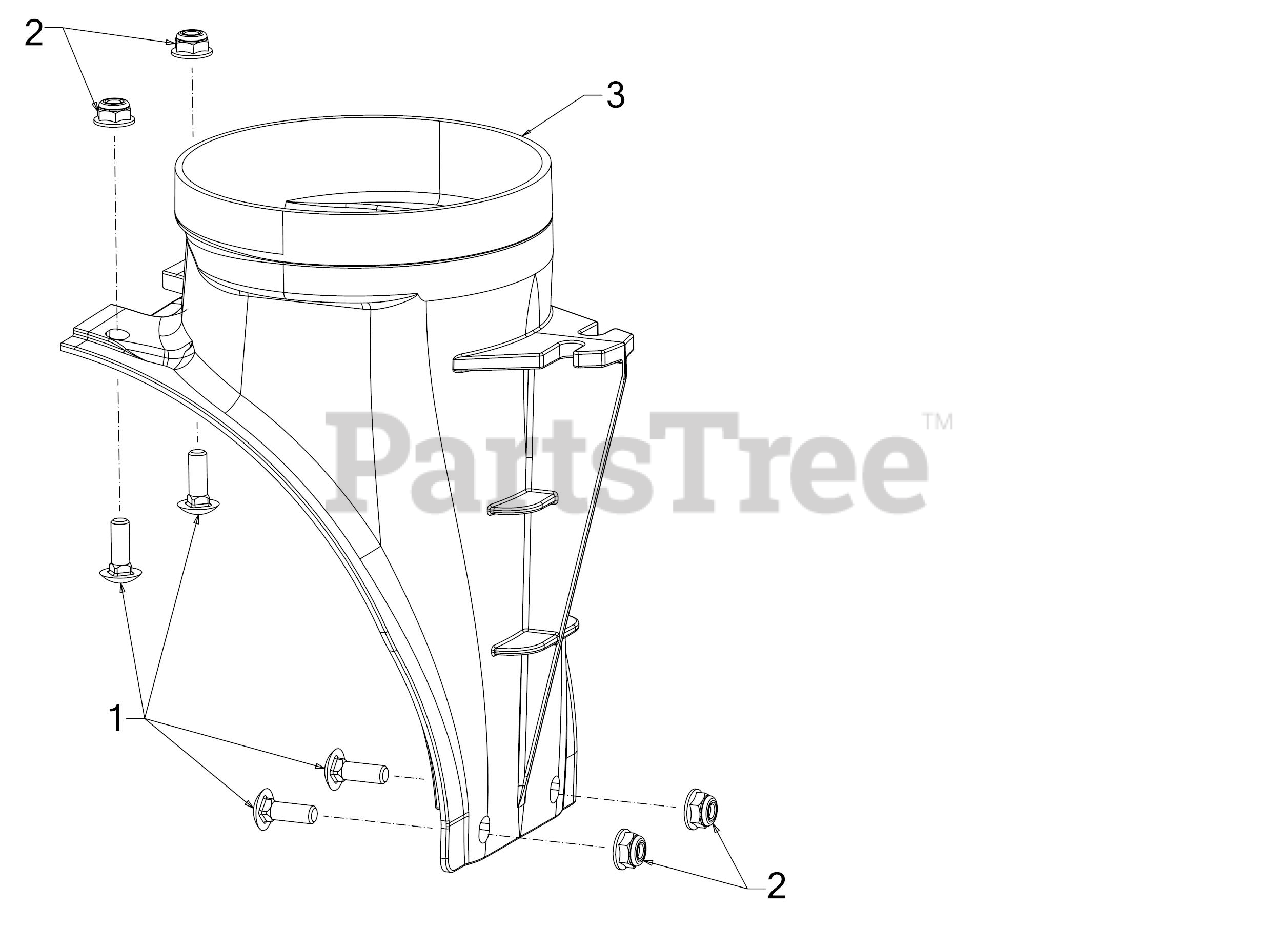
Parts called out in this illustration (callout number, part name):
1	SCREW 1/4-20 x .75 GR5
2	FLANGE LOCK NUT
3	CHUTE ADAPTER 5"
